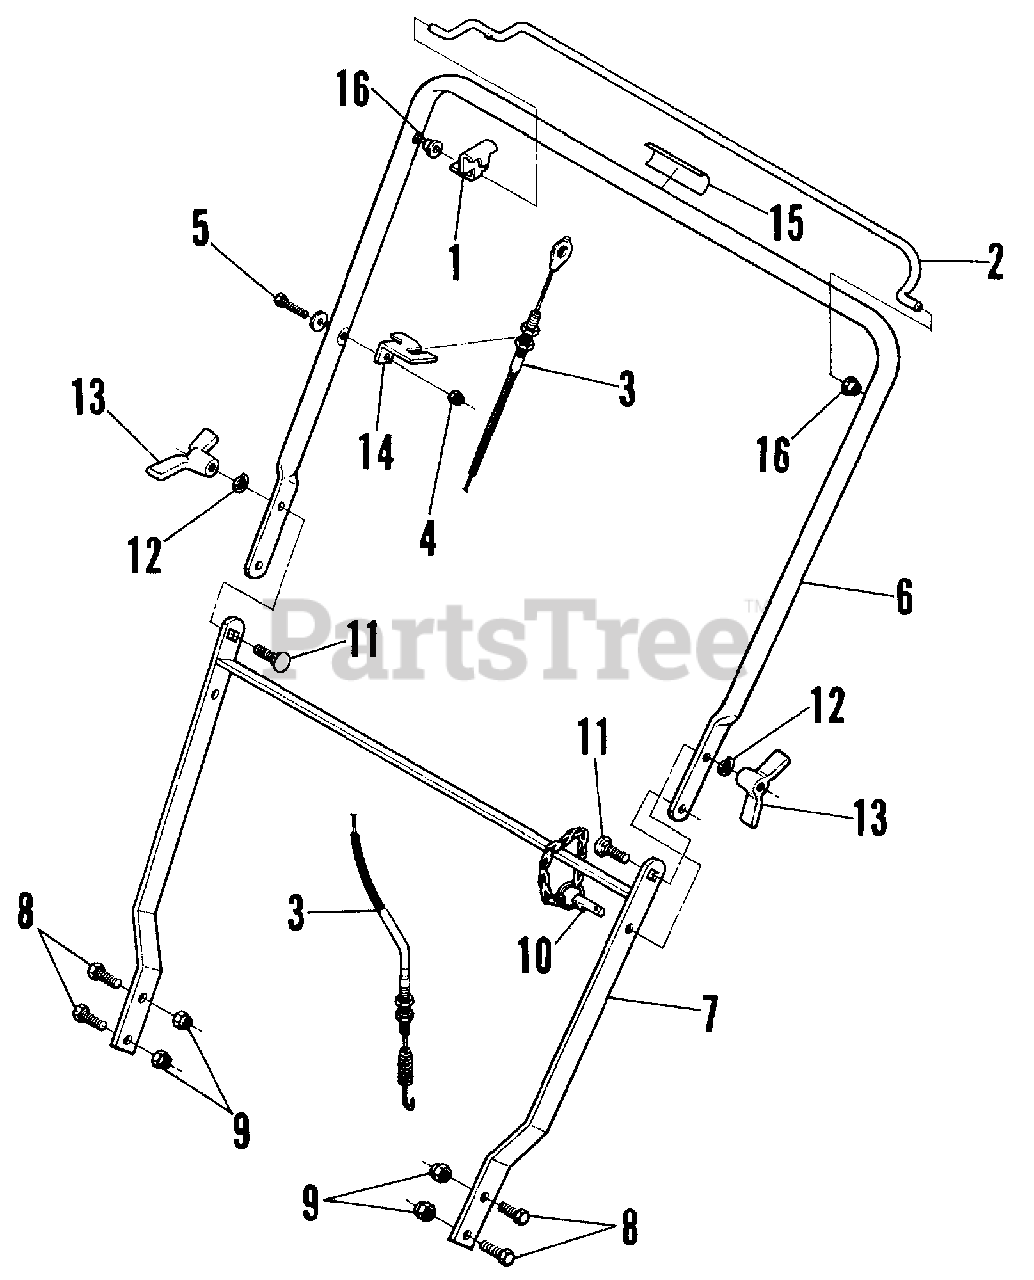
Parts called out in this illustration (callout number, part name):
1	CATCH, Bail
2	BAIL
3	CABLE, Clutch 66.5"
4	NUT, 1/4-20 Hex Nyloc
5	SCREW, 1/4-20 x 1-1/2" Hex Head Cap, Grade 5
6	HANDLE, Upper
7	HANDLE, Lower
8	SCREW, 3/8-16 x 1" Hex Head Cap, Grade 5
9	NUT, 3/8-16 Hex Nyloc
10	PIN, Quick Release Hitch
11	BOLT, 5/16-18 x 1-1/4" Square Neck Carriage
12	WASHER, 5/16 Split Lock
14	MOUNT, Cable
16	BUSHING, 5/16" I.D.
